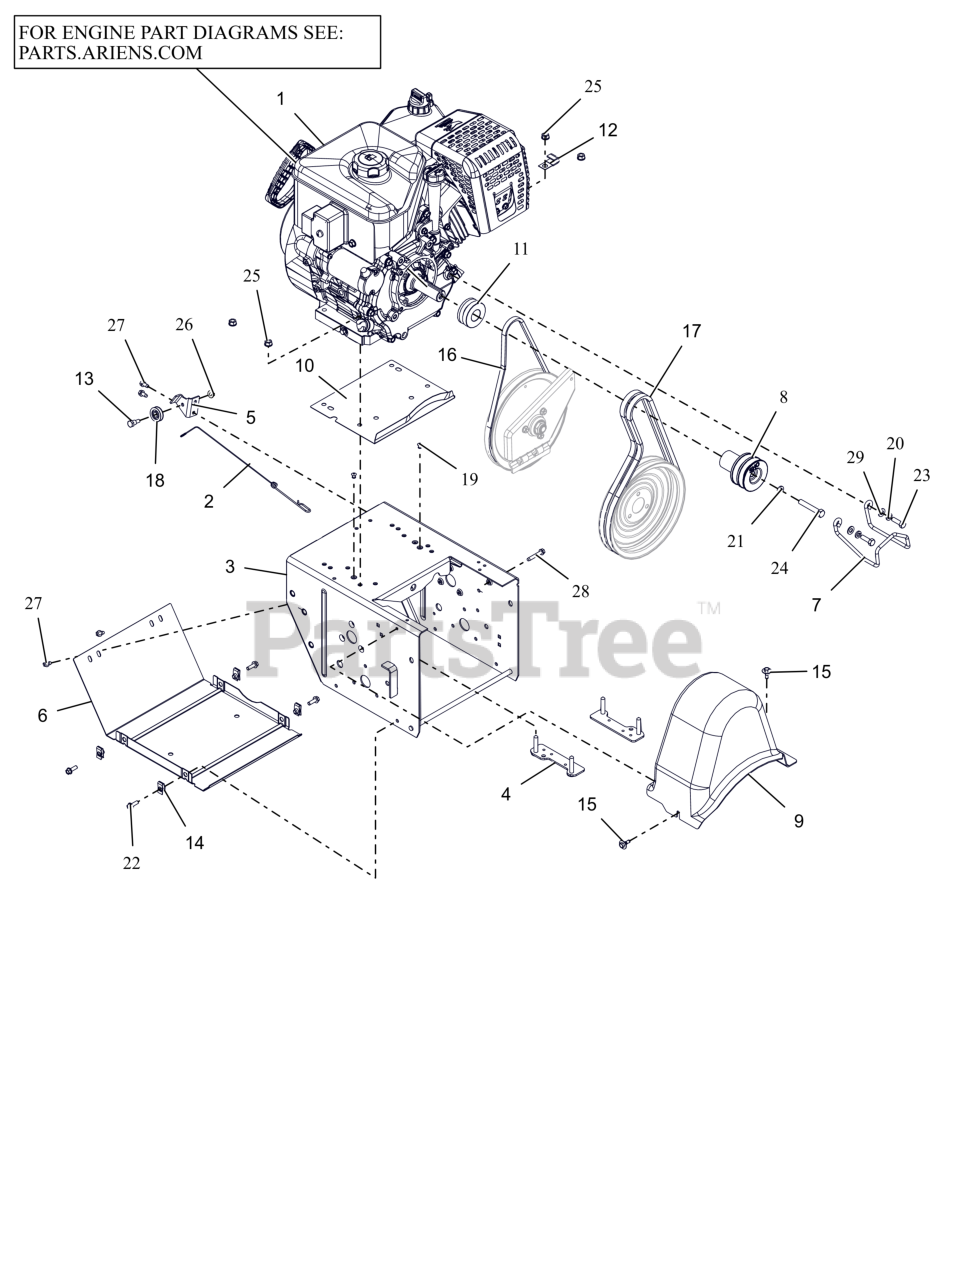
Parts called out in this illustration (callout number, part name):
1	ENGINE, AX420 GEN 3 240V/60W
2	CABLE, LOWER TRACTION,SS & PRO
3	FRAME, MAIN - PRO (WELDMENT)
4	STRAP, BOLT-LARGE
5	BRACKET, CABLE PULLEY
6	COVER, BOTTOM
7	FINGER, BELT
8	SHEAVE,ATTACHMENT-SHO 2 GRV
9	COVER, BELT-LARGE
10	BAFFLE, WATER - LARGE BLOCK
11	SHEAVE, TRACTION (KEYLESS)
12	J-CLAMP
13	BOLT, SHLDR -.375 X .375 X .25-20
14	NUT-RTNR .25-20X.56
15	SCR-TAP .25-20X.5 CAPTIVE
16	V-BELT, 3L-WRAPPED
17	V-BELT, HA-RAW EDGE (SET)
18	PULLEY, CABLE
19	RVT, POP .1875 ZCC
20	WSHR, LK-HVY .312X.097 ZCC
21	WSHR,LK-REG .375X.094 ZCC
22	BLT, HWH .25-20X.75 G5 ZCC
23	BLT, HEX 0.3125-24X1 G5 ZCC
24	BLT, HEX .38-24X2.25 G5 ZCC
25	NUT,LK-CTR-FLG .31-18 GF ZCC
26	NUT-LK-TOP-FLG .250-20 GF ZCC
27	SCR-TAP .25-20X.50 HWH ZCC
28	SCR,TAP .25-20X1.50 HWH TR ZCC
29	WSHR,FLT .344X.688X.065 ZCC
